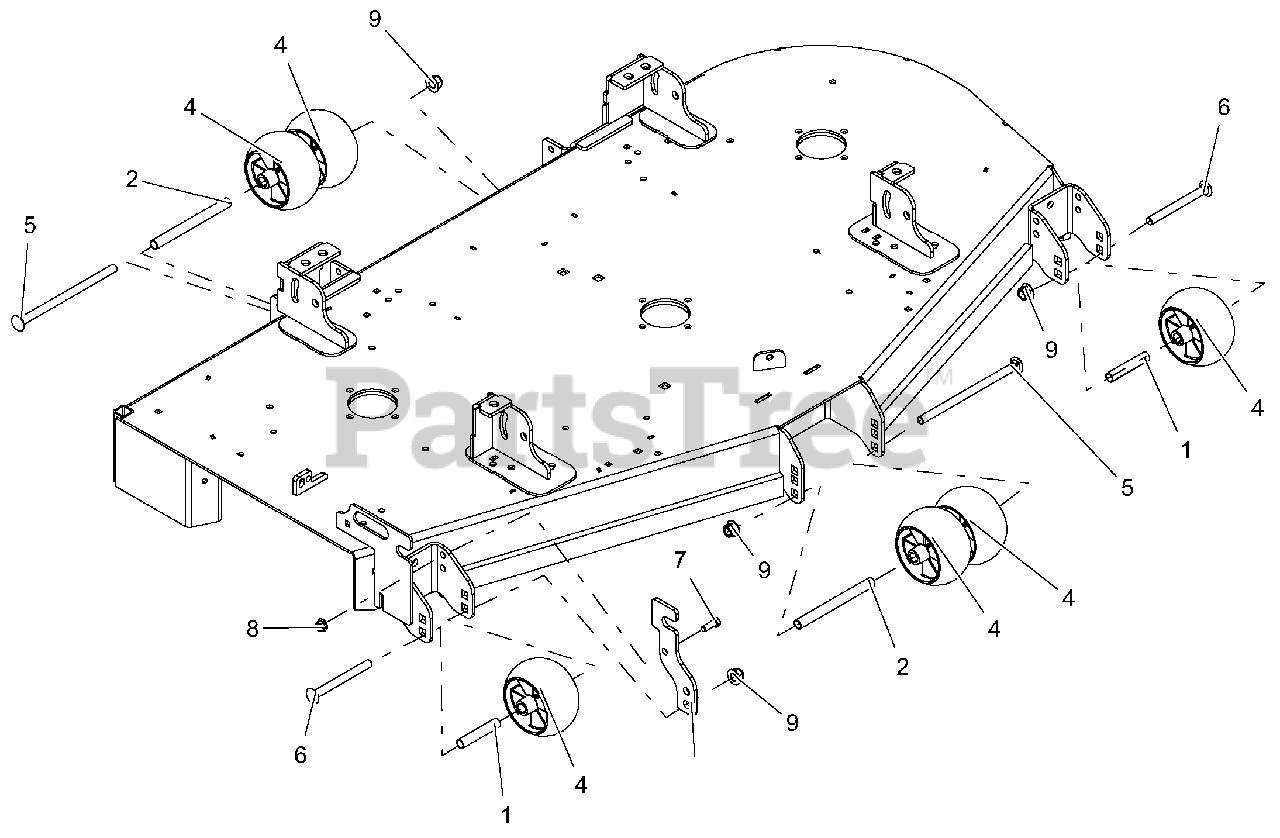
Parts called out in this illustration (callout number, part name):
1	SPACER, .510X.625X3.35
2	SPACER, .510 X .625 X 6.50
4	ANTI-SCALP WHEEL - 5X3 CTR
5	BLT-RDHDSQNK .50-13X8.50 Y
6	BLT-RDHDSQNK .50-13X5.00 G5 YWZC
7	BLT-HEX .38-16X1.00 GR5 YWZC
8	NUT-LK-NYL-FLG .38-16 YWZC
9	NUT-LK-NYL-FLG .50-13 YWZC
